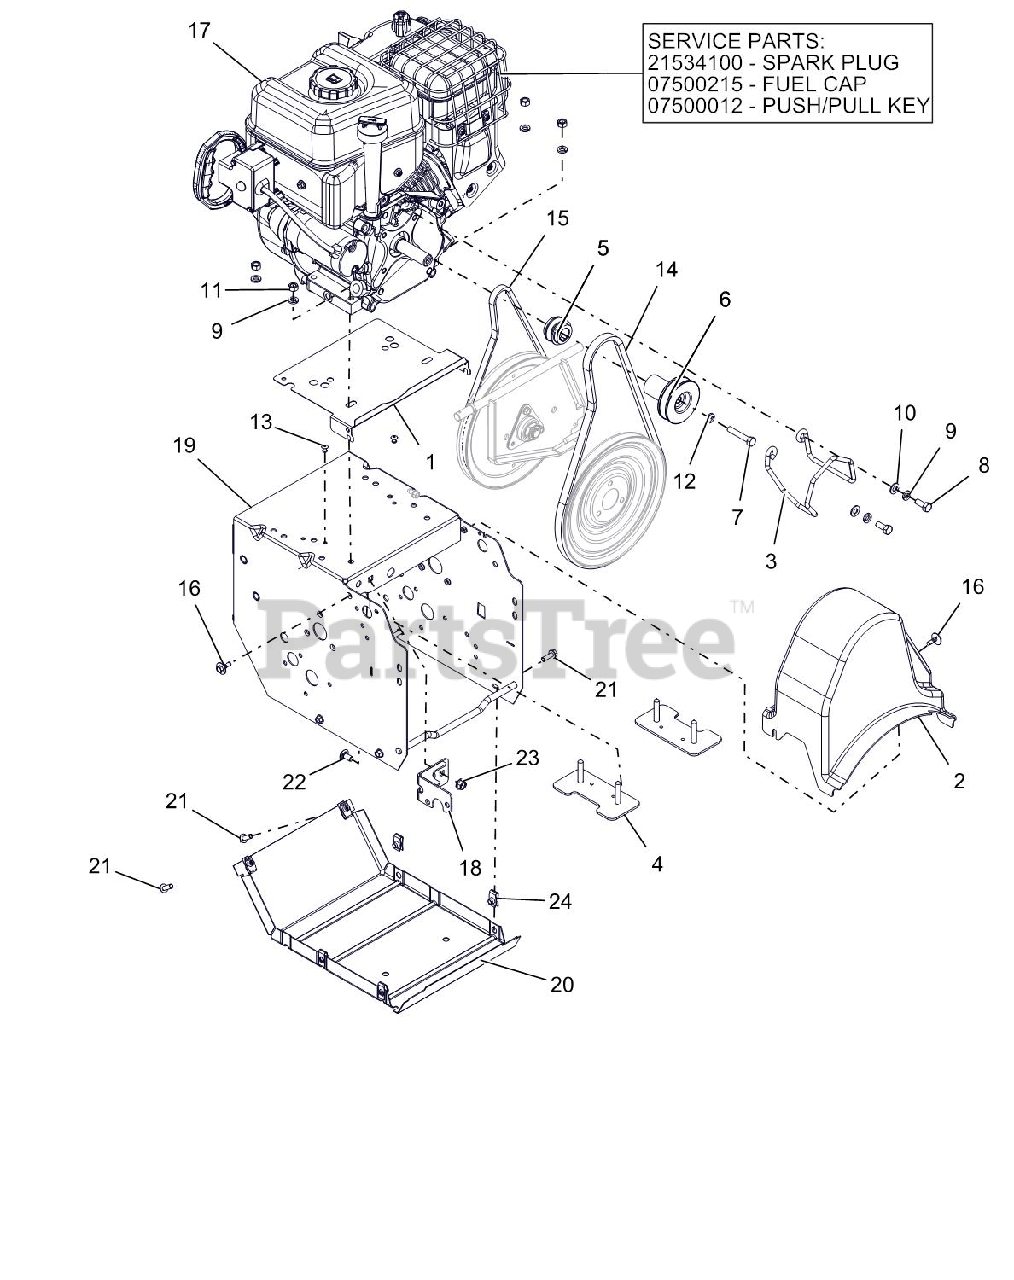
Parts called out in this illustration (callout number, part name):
1	BAFFLE, COMPACT
2	COVER, COMPACT BELT
3	FINGER, BELT
4	STRAP, ENGINE BOLT-WELDMENT
5	TRACTION SHEAVE HALF
6	SHEAVE, AUGER 3/4 - PM
7	@BLT-HEX .31-24X1.75 GR5 YWZC
8	BLT-HEX .31-24X.75 YWZC GR5
9	WSHR-LK .312X.097 HVY YWZC
10	@WSHR-FL-STL.344X.688X.065YWZC
11	@NUT-HEX .31-18 YWZC
12	WSHR-LK .312X.097 HVY YWZC
13	RVT-POP .187 YZ
14	V-BELT, HA-RAW EDGE
15	V-BELT, 3L-WRAPPED
16	SCR-TAP .25-20X.5 CAPTIVE
17	PLUG, SPARK
17	KEY, IGNITION PUSH/PULL B&S
17	CAP, FUEL - BRIGGS & STRATTON
17	ENGINE, BRIGGS 900, RECOIL 60W
18	WELDMENT, FRAME BRACKET
19	FRAME W/ENGINE BOLT STRAPS
20	COVER, BOTTOM
21	BLT-HEX .25-20X.75 HWH YZ GR5
22	@BLT-RHDSSQNK .31-18X.62 G5YZ
23	@NUT-LK-TOP-FLG .31-18 YWZC
24	NUT-RTNR .25-20X.56
